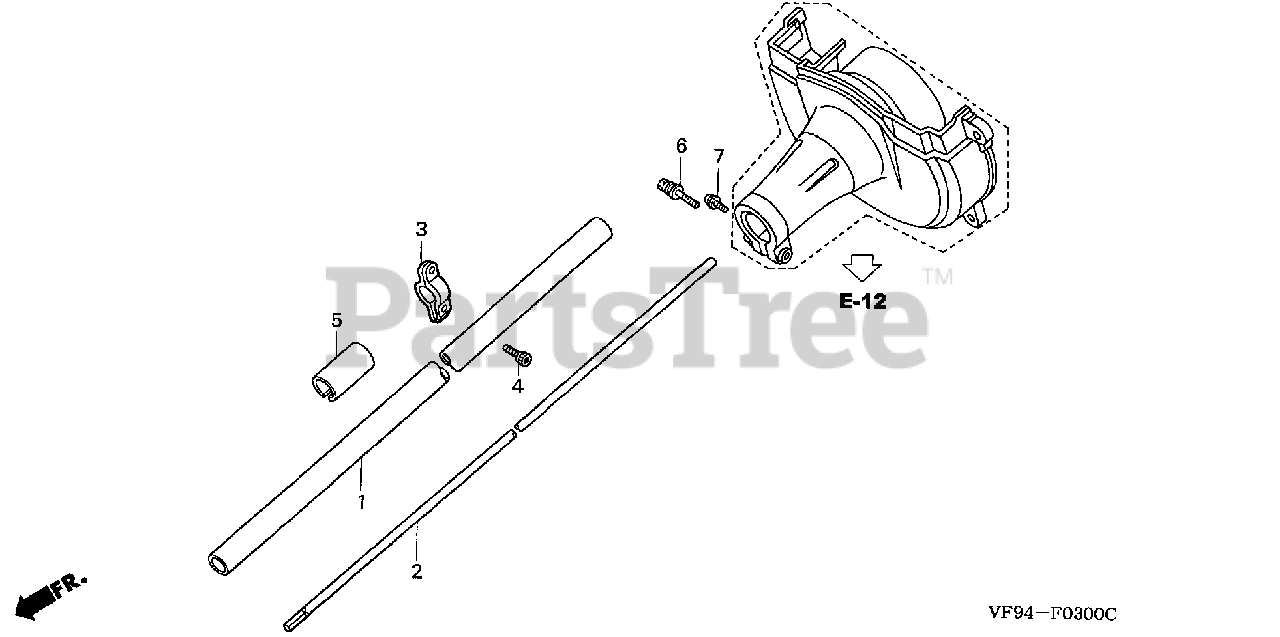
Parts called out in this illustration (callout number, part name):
1	PIPE, FRAME
2	SHAFT, DRIVE
3	HOLDER, HANGER
4	BOLT, SOCKET (6X15)
6	BOLT-WASHER (6X28)
7	SCREW-WASHER (5X10)
